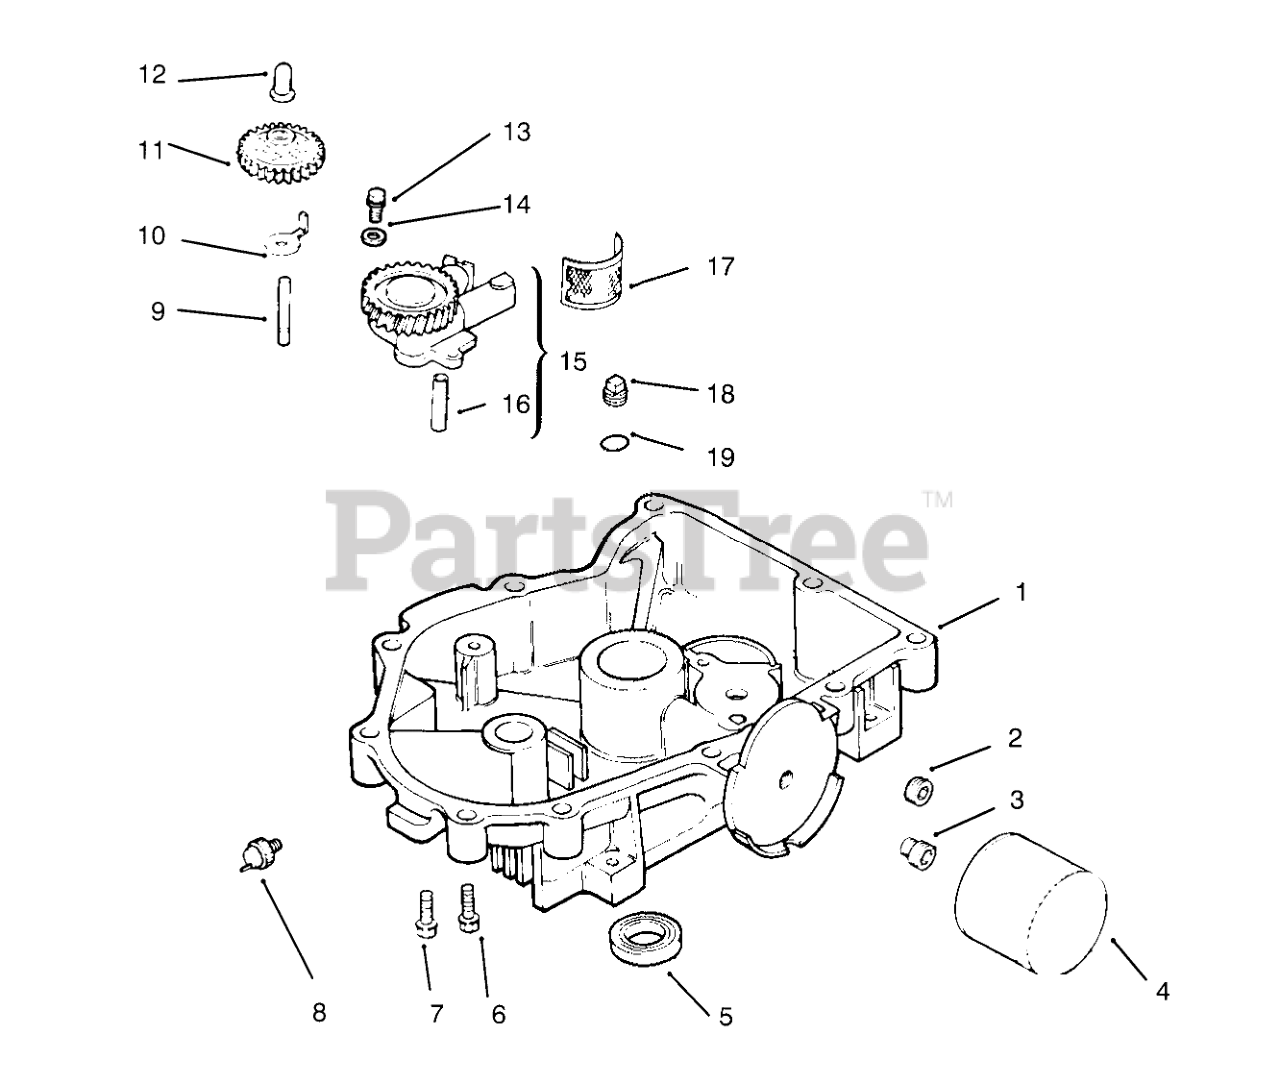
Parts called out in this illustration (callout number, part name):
1	Oil Pan (Only On: 72103)
2	Plug-HS 3/8 NPTF (Only On: 72103)
3	Nipple-Oil Filter (Only On: 72103)
4	Filter-Oil (Only On: 72103)
5	Seal-Oil (Only On: 72103)
6	Screw M8x1.25x45 (Only On: 72103)
7	Screw M8x1.25x45 (Only On: 72103)
8	Switch-Oil Pressure (Only On: 72103)
9	Shaft-Governor Gear (Only On: 72103)
10	Tab-Locking (Only On: 72103)
11	Governor Gear ASM (Only On: 72103)
12	Pin-Governor Regulating (Only On: 72103)
13	Screw-Valve Cover (Only On: 72103)
14	Washer-Governor (Only On: 72103)
15	Oil Pump ASM INCL 16 (Only On: 72103)
16	Tube-Oil Pickup (Only On: 72103)
17	Screen-Oil Pickup (Only On: 72103)
18	Plug-SH 3/8 NPTF (Only On: 72103)
19	O Ring (Only On: 72103)
